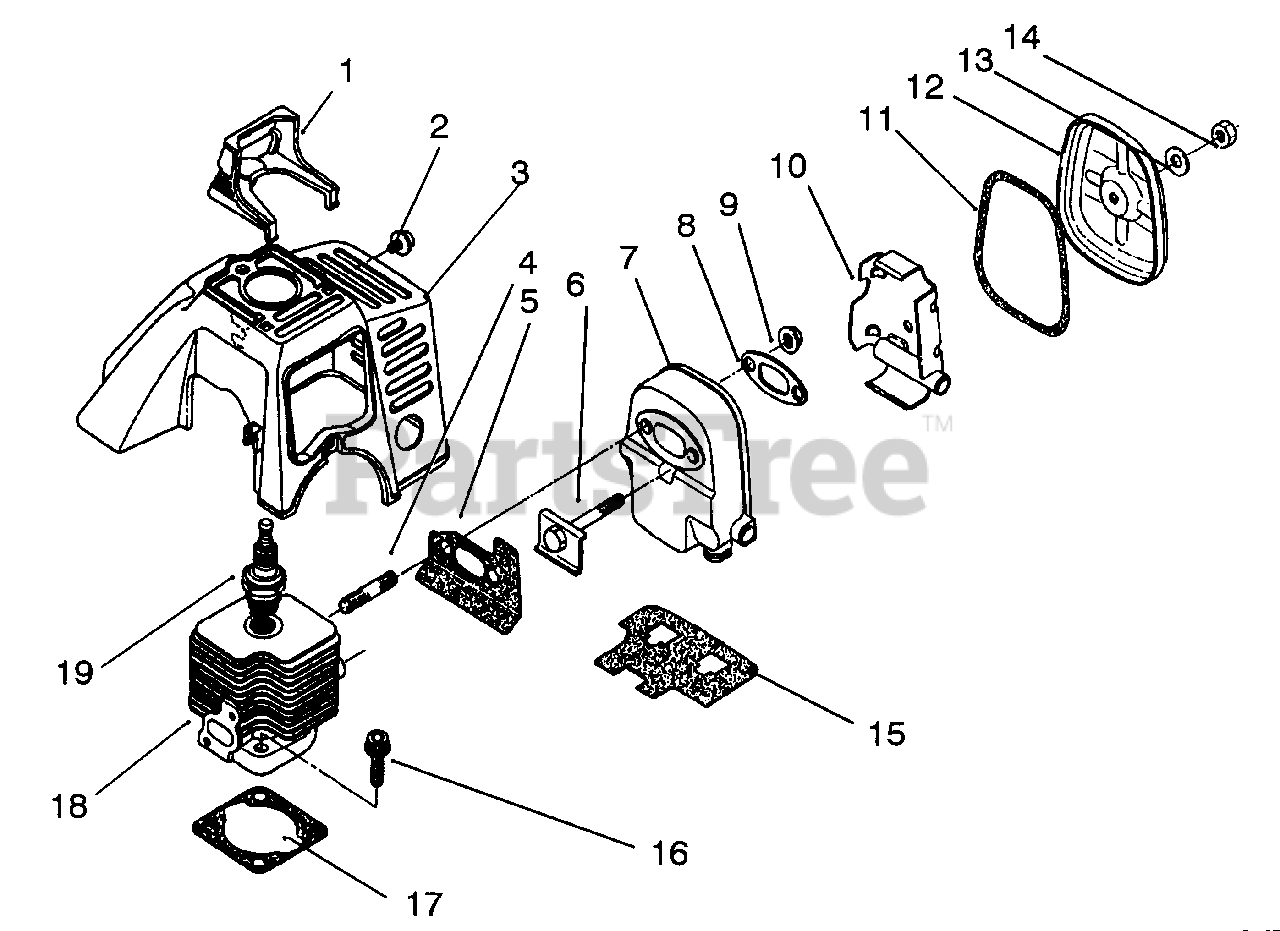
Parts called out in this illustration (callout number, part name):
1	Guard-Spark Plug
2	Screw/Washer
3	Cover-Top
5	Gasket-Muffler
7	Body-Muffler
11	Gasket-Muffler Seal
12	Lid-Muffler
16	Bolt-Flange
17	Gasket-Cylinder
18	Cylinder
19	Spark Plug
